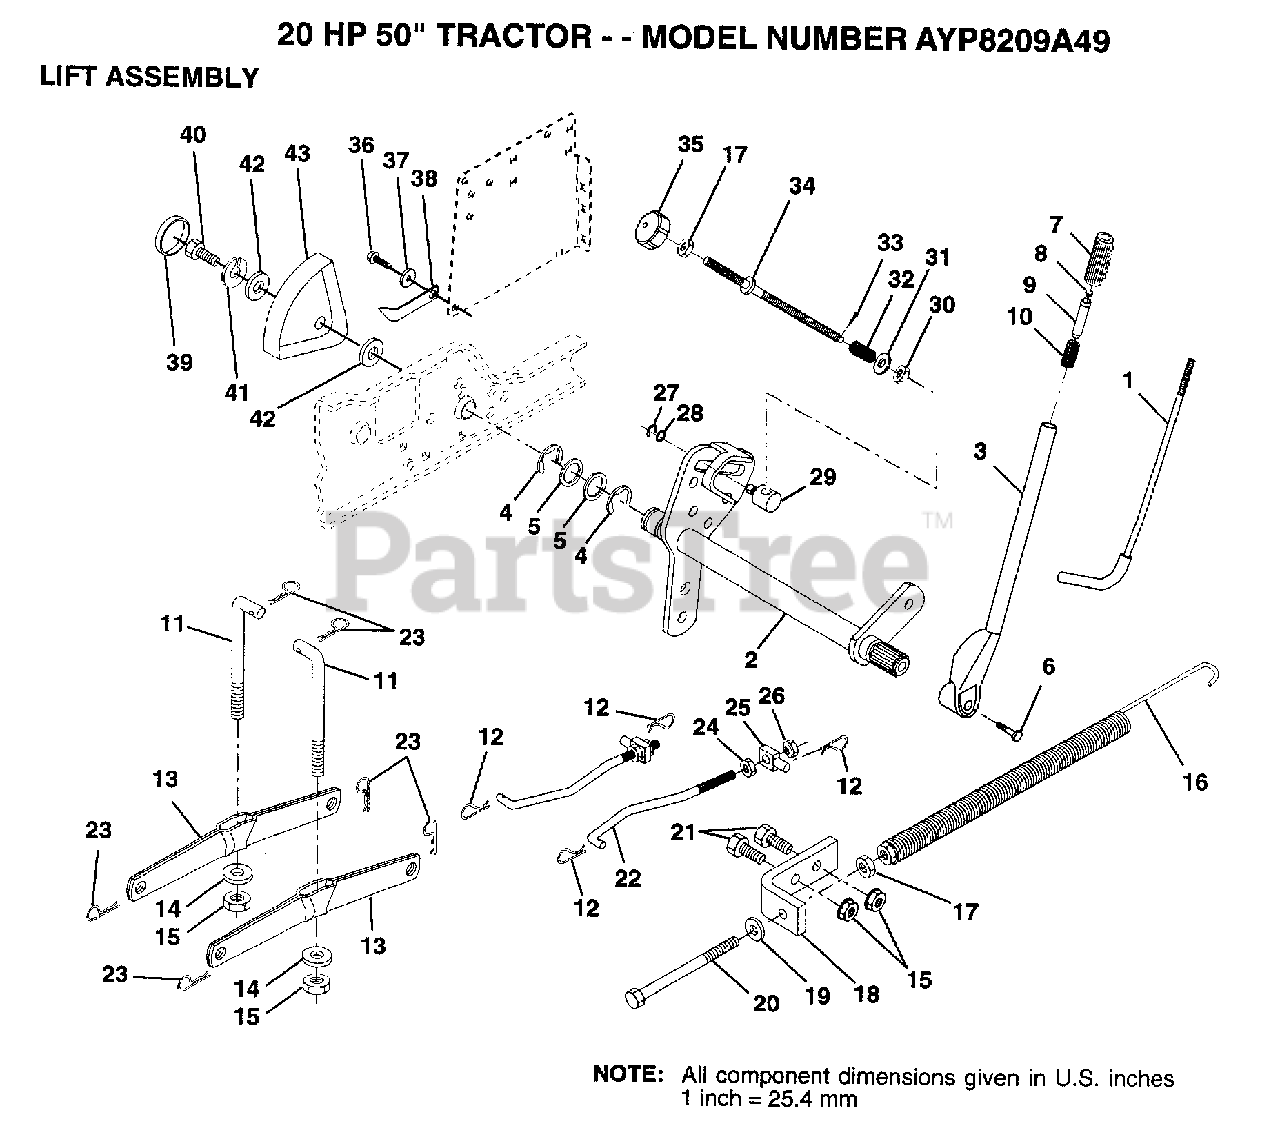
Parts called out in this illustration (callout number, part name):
1	LEVER ROD LT
4	E-RING
5	WASHER
6	"BOLT,HEX"
7	GRIP HANDLE
10	SPRING T
12	RETAINER.SPRING
14	BEARING PVT LH
15	NUT
17	NUT
19	WASHER
20	BOLT-ADJ SPRING T
21	BOLT
22	LINK.FRONT
24	NUT
25	TRUNION
26	NUT.LK.W/WSH.1/2.
27	KLIP RING
28	WASHER
29	TRUNION LT
30	NUT T
31	WASHER
32	SPRING.COMP.INF.H
34	ROD.ADJ.LIFT
35	KNOB INF 3/8-16
36	SCREW
37	WASHER T
38	POINTER HGT IND
39	"PLUG,HOLE"
41	LOCKWASHER
42	WASHER
43	HEIGHT INDICATOR
